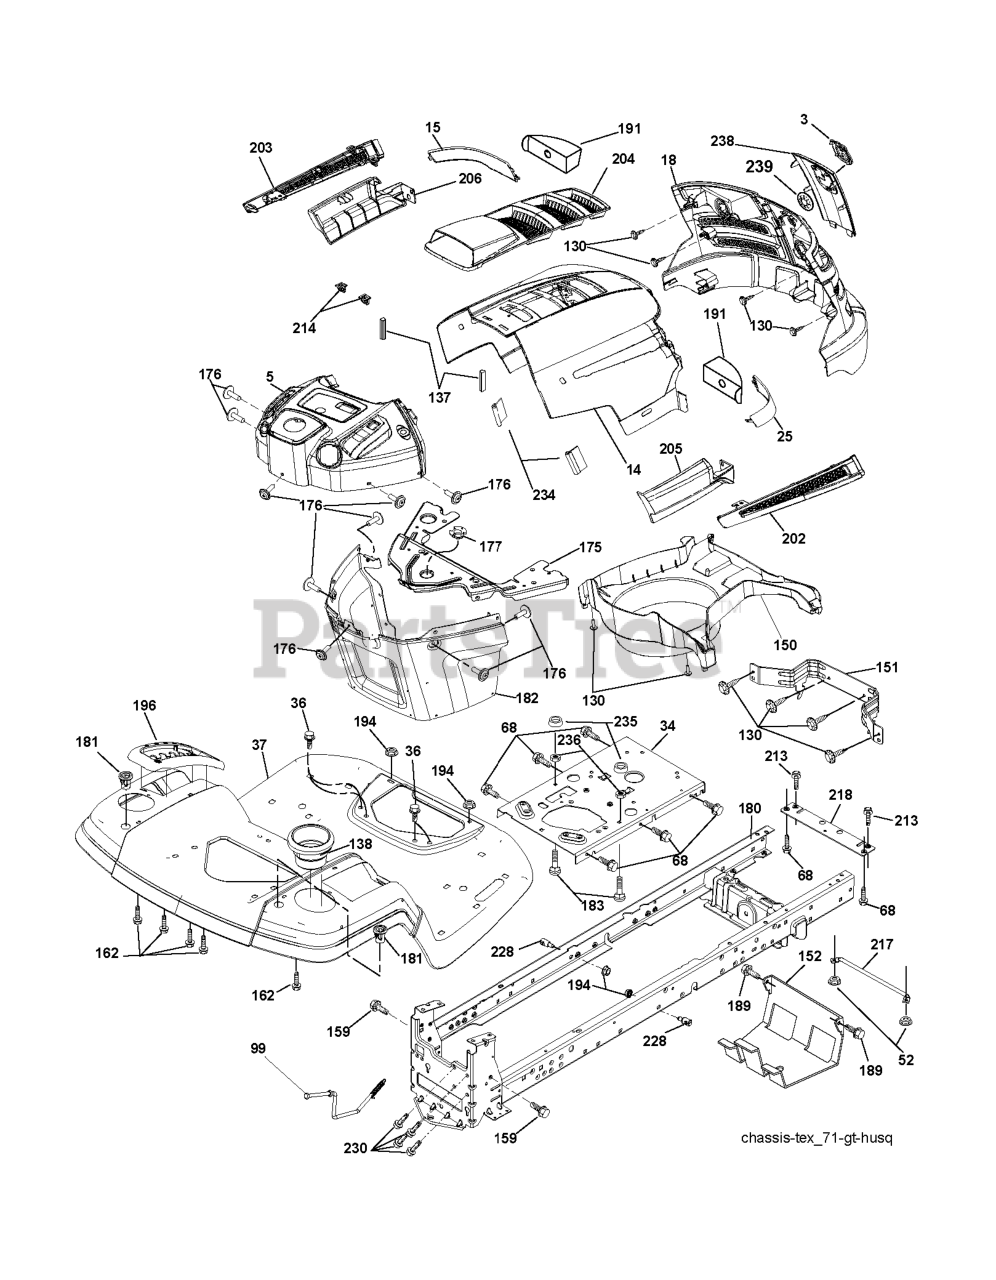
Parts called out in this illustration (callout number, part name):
3	RP LOGO
5	DASH
14	HOOD
15	LENS.HUSQVARNA LT.LH
18	RP GRILLE/LENS ASM.
25	LENS.HUSQVARNA LT.RH
34	PLATE.ENGINE.WELDED.CHASSIS
36	SCREW 5/16"
37	FENDER.REAR.ORANGE
52	LOCKNUT
68	Screw 5/16-18 x 1/2 Hex, Self Tapping 5/16-18 x 1/2
99	ROD.ASM.BYPASS.0510.HYDRO.LT
130	SCREW
137	BUMPER DASH
138	CUPHOLDER.TL.TEX.418
151	BRACKET PIVOT
152	SHIELD.BROWNING.W/TEX
159	SCREW, 3/8-16X3/4
162	SCREW.HI-LO.CONSOLE
175	CROSSMEMBER
176	SCREW.#10-24X5/8.RN.QU
177	BUSHING STEERING
180	CHASSIS
181	BUSHING.MNT.FEND.CRGO.
182	DASH LOWER
183	BOLT.5/16-18X1-1/4 FULL.THREAD
189	SCREW
191	INSERT REFLECTIVE
194	NUT LOCK HEX FLANGE 5/16-18
196	CONSOLE.ASM.DECK.LIFT.
202	VENT SIDE HOOD RH
203	VENT SIDE HOOD LH
204	VENT TOP HOOD
205	SKIRT SIDE RH
206	SKIRT SIDE LH
213	BOLT
214	CLIP.RETAINER.TINNER.
217	ROD.PIVOT.HOOD
218	X-PIECE.HOOD.STOP.NON/
228	STUD.FASTNER.W/ANTI-ROTATE
230	SHOULDER BOLT 5/16-18TT
234	BUMPER.HOOD.TEX.HUSQVARNA
235	SPACER FENDER
236	NUT.CENTERLOCK.5/16-
238	TRIM
